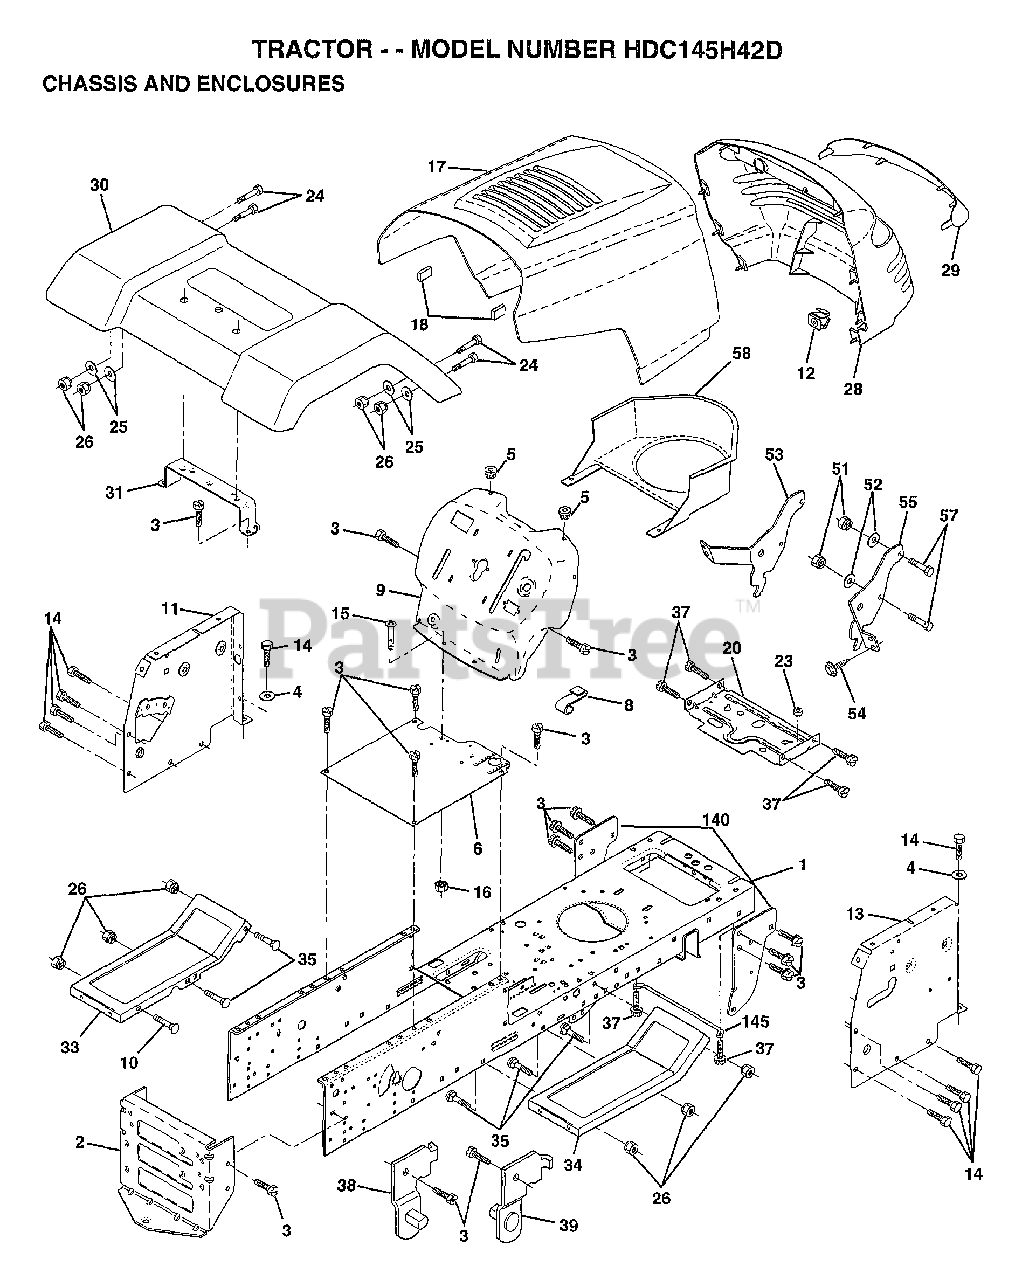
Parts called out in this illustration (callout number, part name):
1	CHASSIS ASM
3	SCREW
4	WASHER
5	BUMPER-HOOD/DASH
6	SADDLE
8	CLIP.RETAINER
9	DASH.SILKSCREENED
11	"PANEL-DASH,LH"
12	CLIP.TINNERMAN
14	SCREW LT
15	SCREW
17	"HOOD W/TRIM,MS428"
20	"PLATE-MTG,BATT/FU"
24	BOLT
25	WASHER
26	NUT
28	GRILLE-MS428
29	LENS GRILLE
30	FENDER ASM LT W/S
31	BRKT FENDER
33	FOOTREST LH
34	FOOTREST RH
35	BOLT
37	SCREW LT
38	BRACKET ASM LH
39	BRACKET ASM RH
51	NUT
52	WASHER
53	BRACKET.GRILLE.LH
55	BRACKET.GRILLE.RH
58	AIR DUCT
140	BRKT SUSPENSION
145	"ROD POVOT,CHASSIS"
